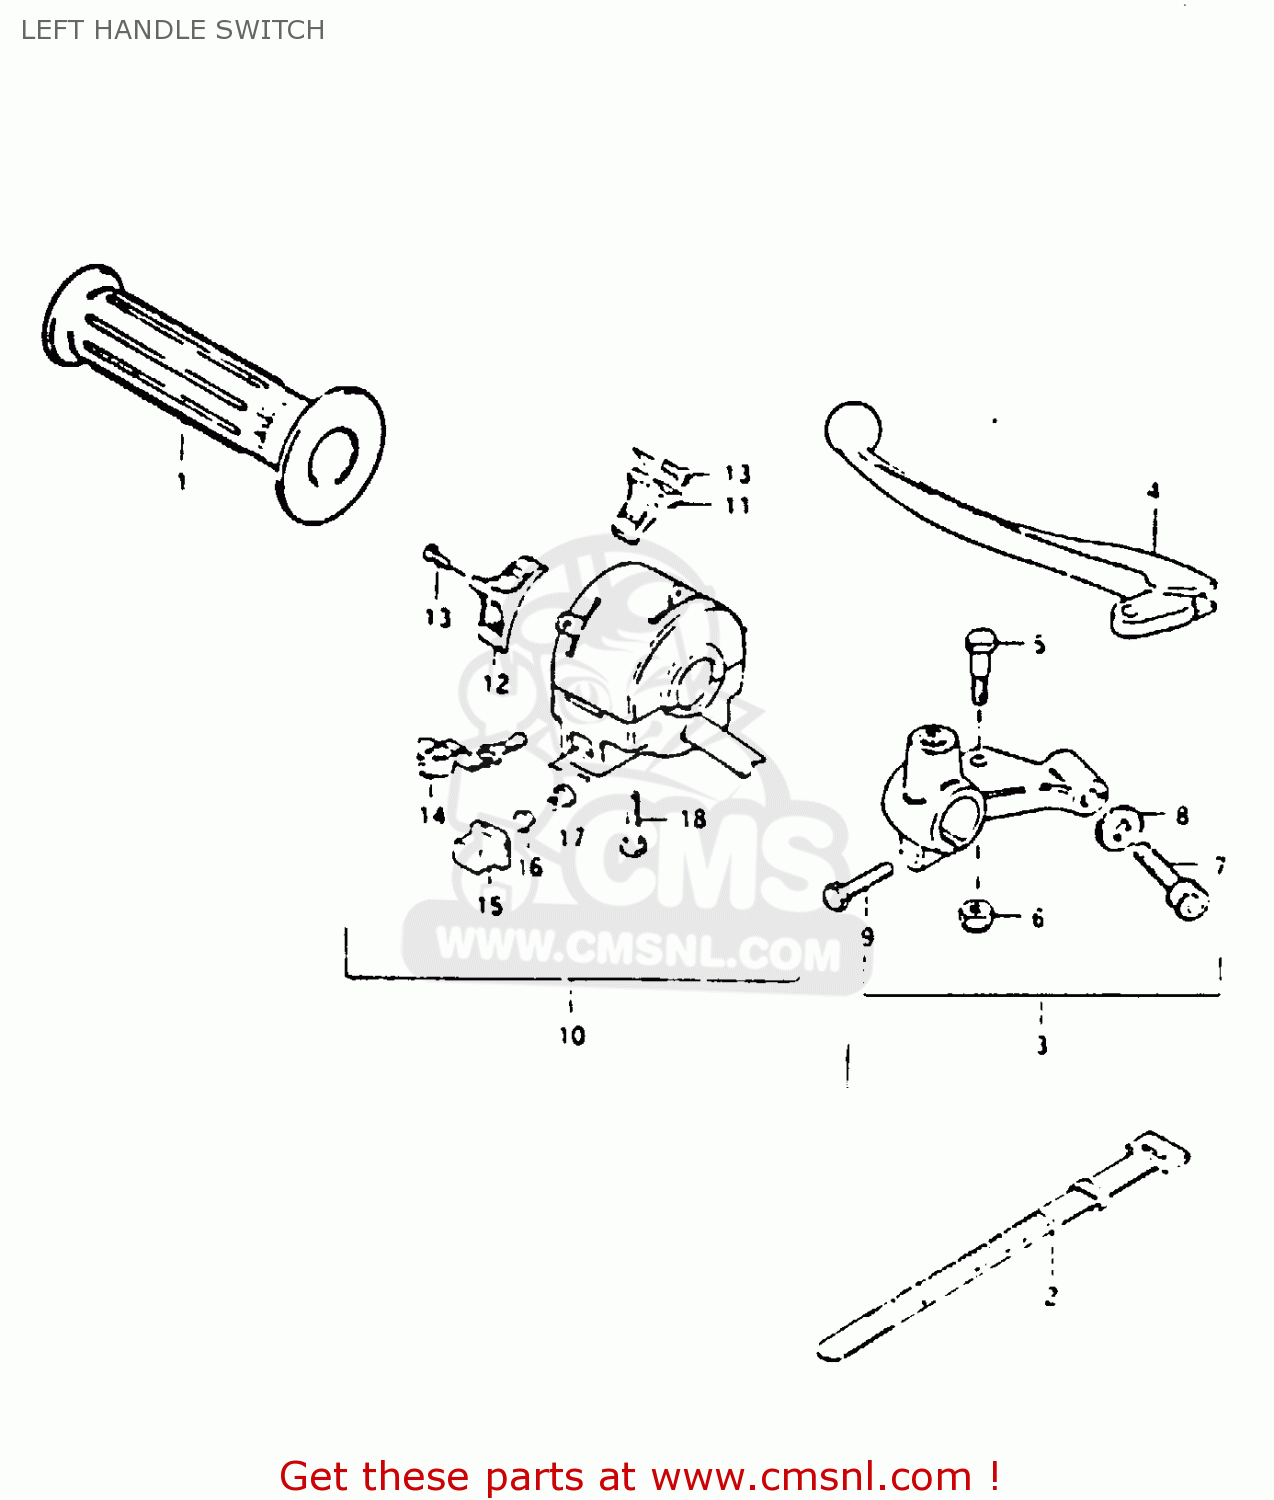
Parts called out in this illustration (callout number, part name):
1	GRIP,L
2	CLAMP(L:120)
3	LEVER ASSEMBLY,CLUTCH
4	LEVER,CLUTCH
5	BOLT,LEVER
6	NUT 6MM
7	ADJUSTER,CABLE
8	NUT,CABLE ADJUSTER
9	BOLT
10	SWITCH ASSY,HANDLE,L
11	KNOB,LIGHTING SWITCH
12	KNOB,DIMMER SWITCH
13	SCREW
14	KNOB,TURNSIGNAL
15	BUTTON,HORN
16	CONTACT
17	SPRING
18	SCREW
